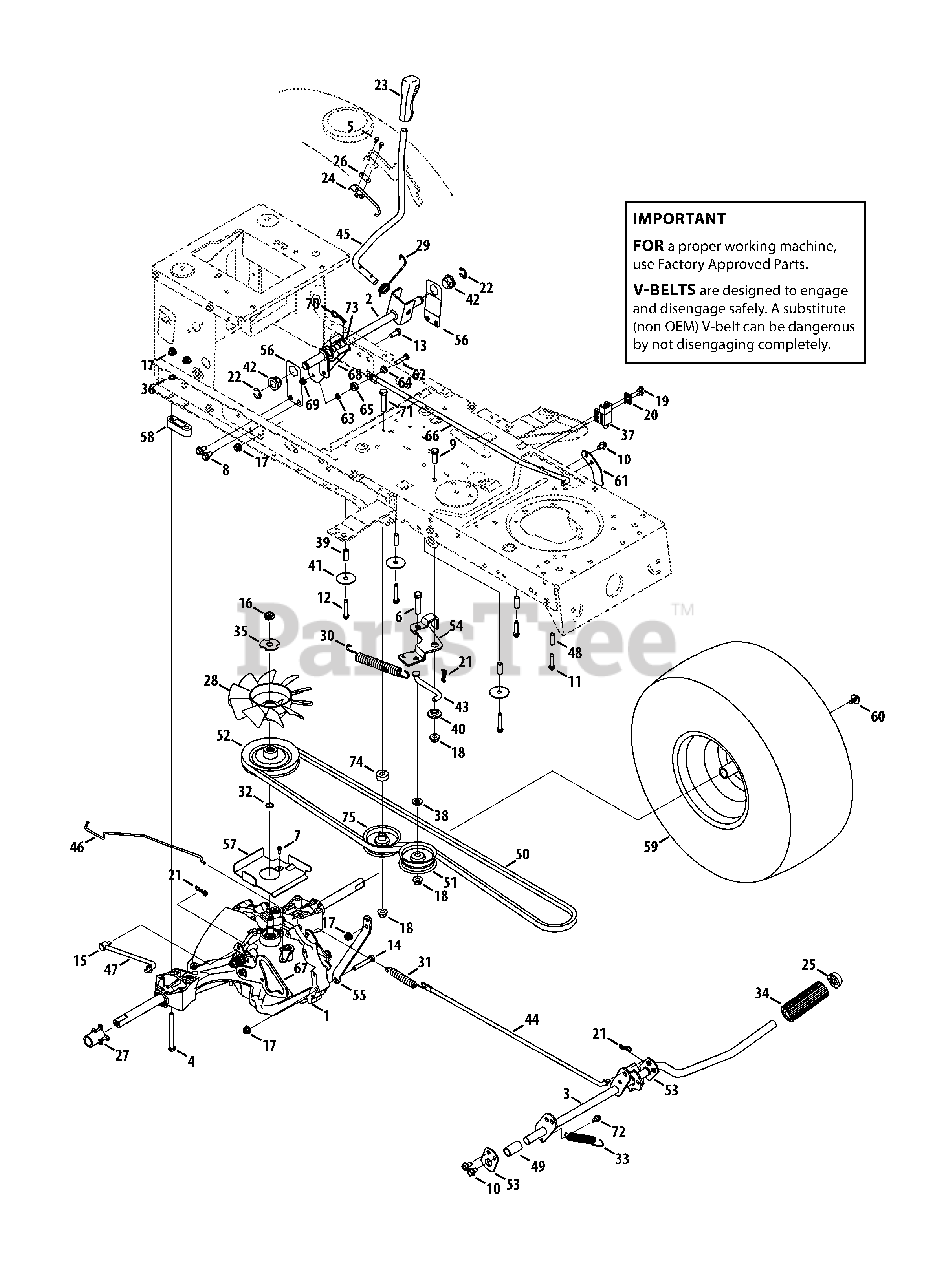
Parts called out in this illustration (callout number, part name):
1	Hydro Transmission
2	Hydro Handle Control Assembly
3	Hydro Pedal Assembly
4	Hex Screw, 5/16-18 x 3.5
5	Screw, #8-18:0.500
6	Hex Screw, 3/8-16:1.75
7	Screw, #10-16:0.500
8	Screw, 5/16-18:.750
9	Hex Screw, 3/8-16:1.00
10	Screw, 5/16-18:0.625
11	Screw, 1/4-20:1.250
12	Screw, 1/4-20 x 1.75
13	Hex Screw, 5/16-18:.75
14	Screw, 5/16-18 x 2.00
15	Ferrule, 5/16-24 X .312 DIA.
16	Jamlock Nut, 1/2-20
17	Flangelock Nut, 5/16-18
18	Flangelock Nut, 3/8-16
20	Plate Switch
21	Cotter Pin, Bow Tie
22	E Rign, .625 DIA
23	Handle Grip
24	Hydro Spring Switch
25	Push Cap, 5/8
26	Insulator Plate Nut
27	Sleeve, .765 ID X 2.11 LG
29	Torsion Spring
30	Extension Spring, .75 DIA. X 6.02
31	Extension Spring, .59 OD X 4.00 LG
32	Wire Ring
33	Extension Spring, .63 DIA X 4.95 LG
34	Foot Pad, 4.0
35	Lock Washer, TRANS HYDRO
36	Lock Washer, 5/16 EXT TOOTH
37	Switch Interlock
38	Flat Washer, .407X.812X.135:HT
39	Spacer, .260 x .372 x 1.420
40	Shldr Spacer, 1.375 ID X .380 x 1.54
41	Flat Washer, .350 x 1.59 x .062
42	Hex Flange Bearing
43	Declutching Rod
44	Brake Rod
45	Hydro Control Handle
46	Hydro Bypass Rod
47	Hydro Control Rod
48	Spacer, .260 x .375 x 1.030 LG
49	Spacer, .640 ID X .76 OD X 1.60
50	V Belt, 4L SEC X 84.17
51	Flat Idler Pulley 2.75 OD
52	Input Pulley
53	Support Pedal Bracket
55	Torque Bracket
56	Handle Bracket
57	Belt Support Bracket
58	Spacer, T-Axle
59	Wheel, 20 x 8 x 8 - Grey
60	Screw, 5/16-24 x .750
62	Hex Screw, 1/4-20 x 1.25
63	Flat Washer, .281 x .500 x .063
64	Shoulder Spacer, .375 x .625 x .20
65	Ball Bearing, .25 x .6875 x .25
66	Hydro Rod, RTN
67	Cam Bracket, RTN
68	Pivot Bracket, RTN
69	Nut, Flange Lock, 1/4-20, GrF
70	Click Pin, .092 x 1.64 LG
71	Hex Screw, 3/8-16 x 2.00
72	Shoulder Screw, 1/4-20 x 0.50
73	Hex Flange Bearing, .628 ID
74	Spacer, .406 ID x 1.00 OD x .38
75	V Pulley 3.06 OD
